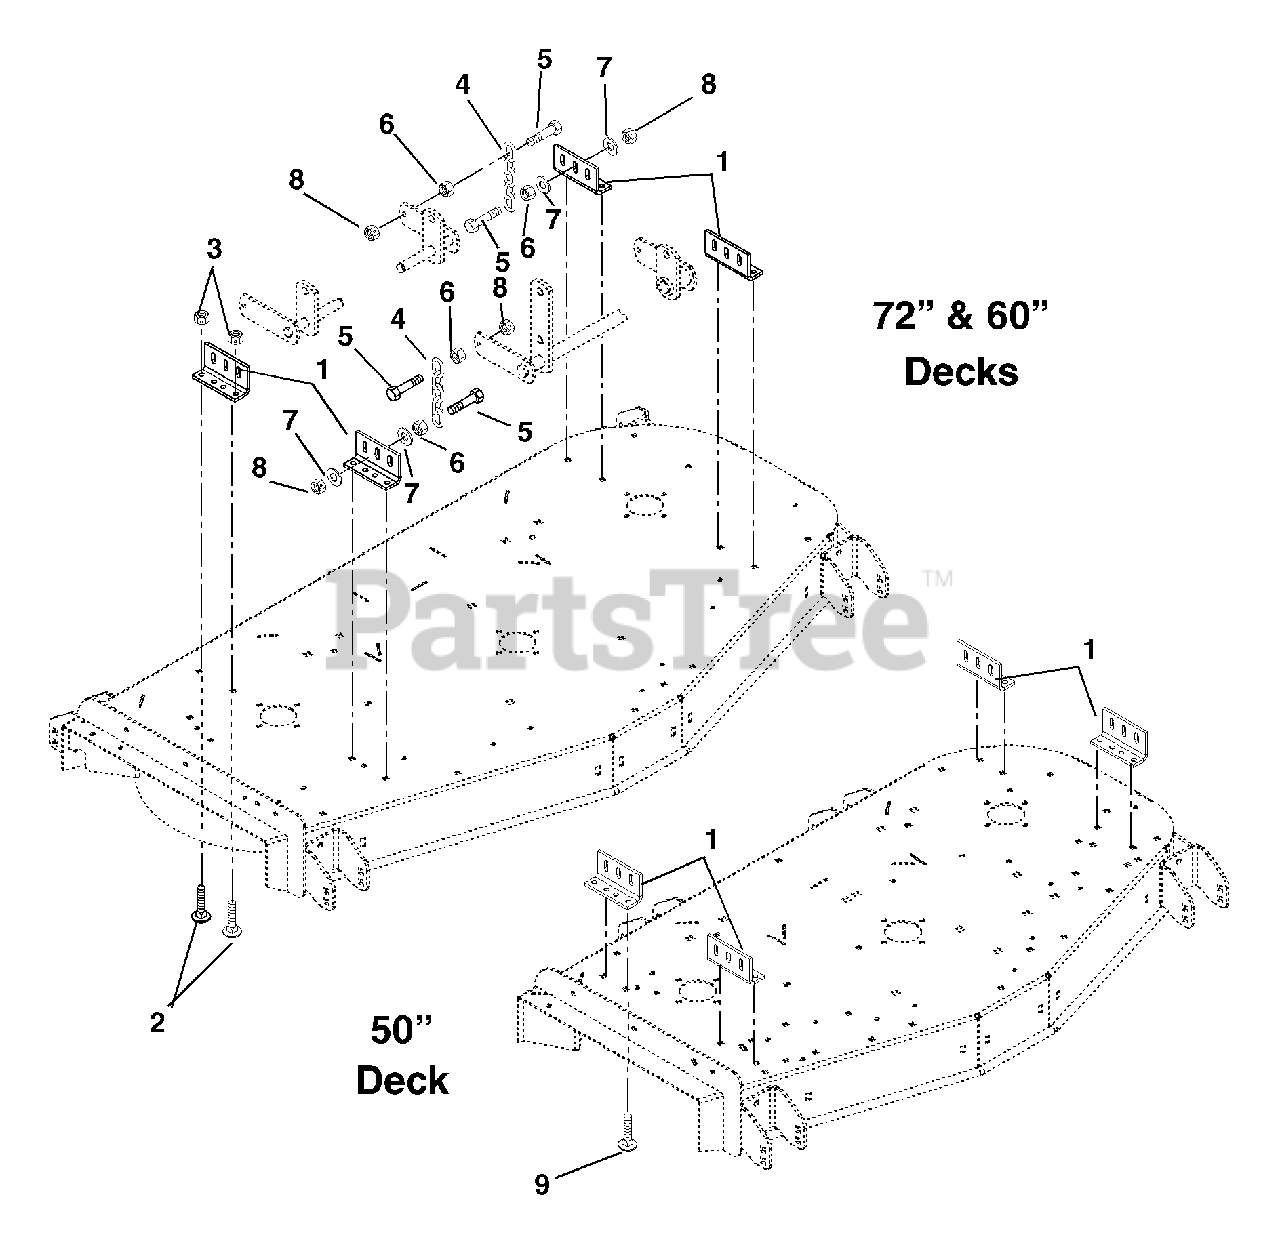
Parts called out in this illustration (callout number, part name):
1	Bracket, Mower Mounting
2	Bolt-Round Head Square Neck .38-16 x 1.25 Grade 2 (60" Deck)
2	Bolt-Round Head Square Neck .38-16 x 1.25 Grade 2 (50" Deck)
3	Nut-Locking-Nylon .38-16
4	Chain, Link
5	Bolt-Hex .38-16 x 1.50 Grade 5
6	Nut-Hex .38-16
7	Washer-Flat-Steel .406 x .812 x .065
8	Nut-Locking-Center .38-16
9	Bolt-Round Head Square Neck .38-16 x 1.50 Grade 2 (50" Deck)
